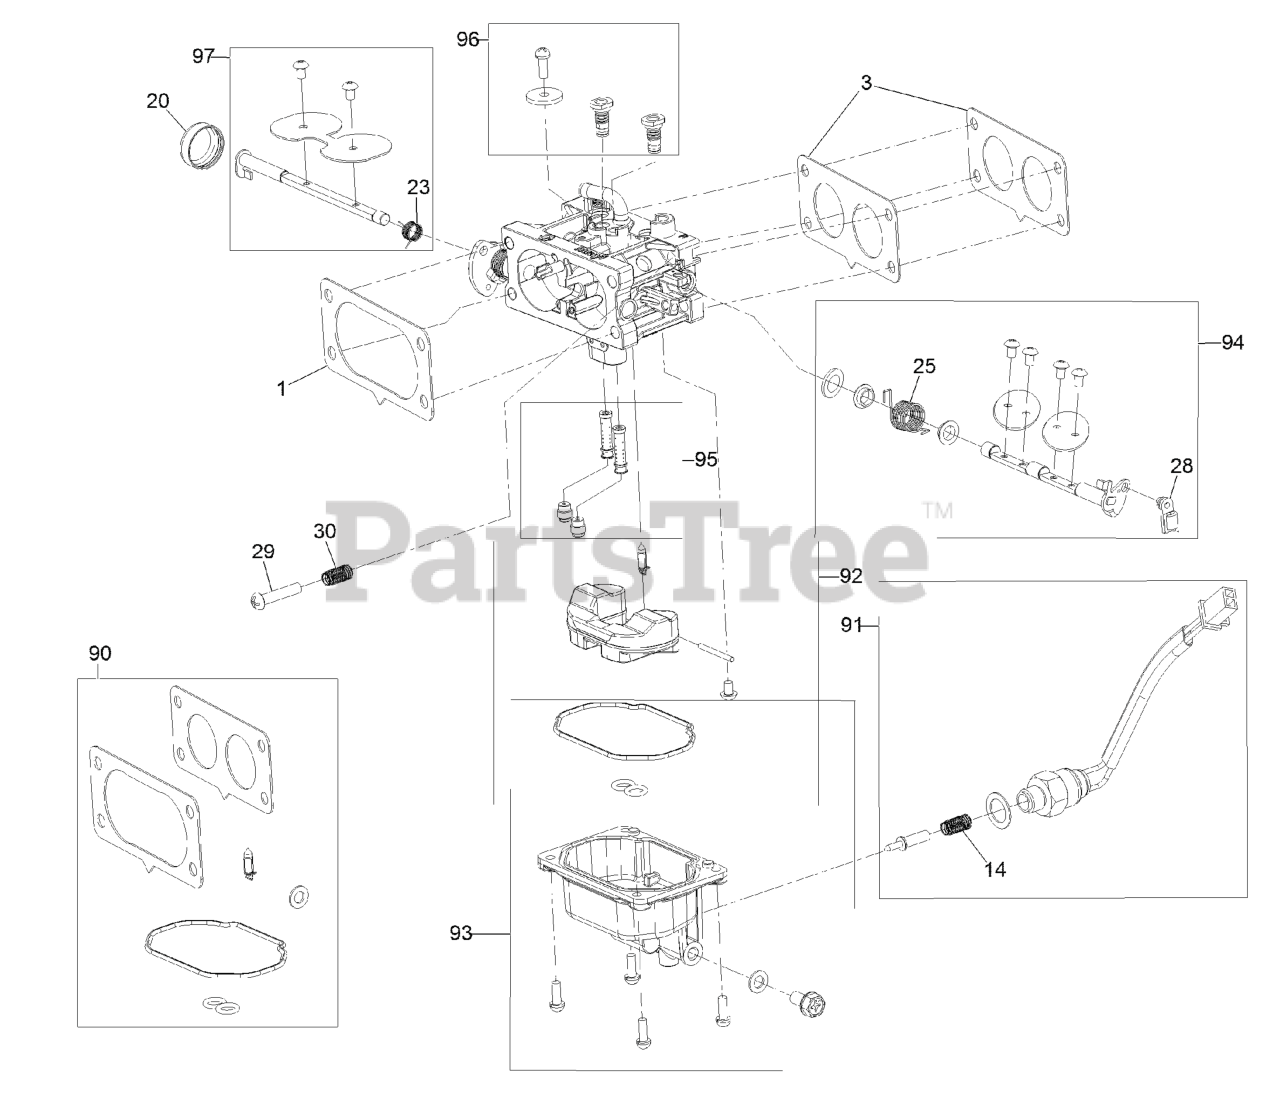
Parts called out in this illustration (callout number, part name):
1	GASKET-CARBURETOR
3	GASKET-CARBURETOR
20	COVER-SHAFT, CHOKE
28	CLAMP-LOCK
29	SCREW-PPH
90	CARBURETOR REPAIR KIT
91	SOLENOID KIT
92	FLOAT KIT
93	BOWL KIT
94	THROTTLE SHAFT KIT
95	NOZZLE AND JET KIT
96	IDLE JET KIT
97	CHOKE SHAFT KIT
